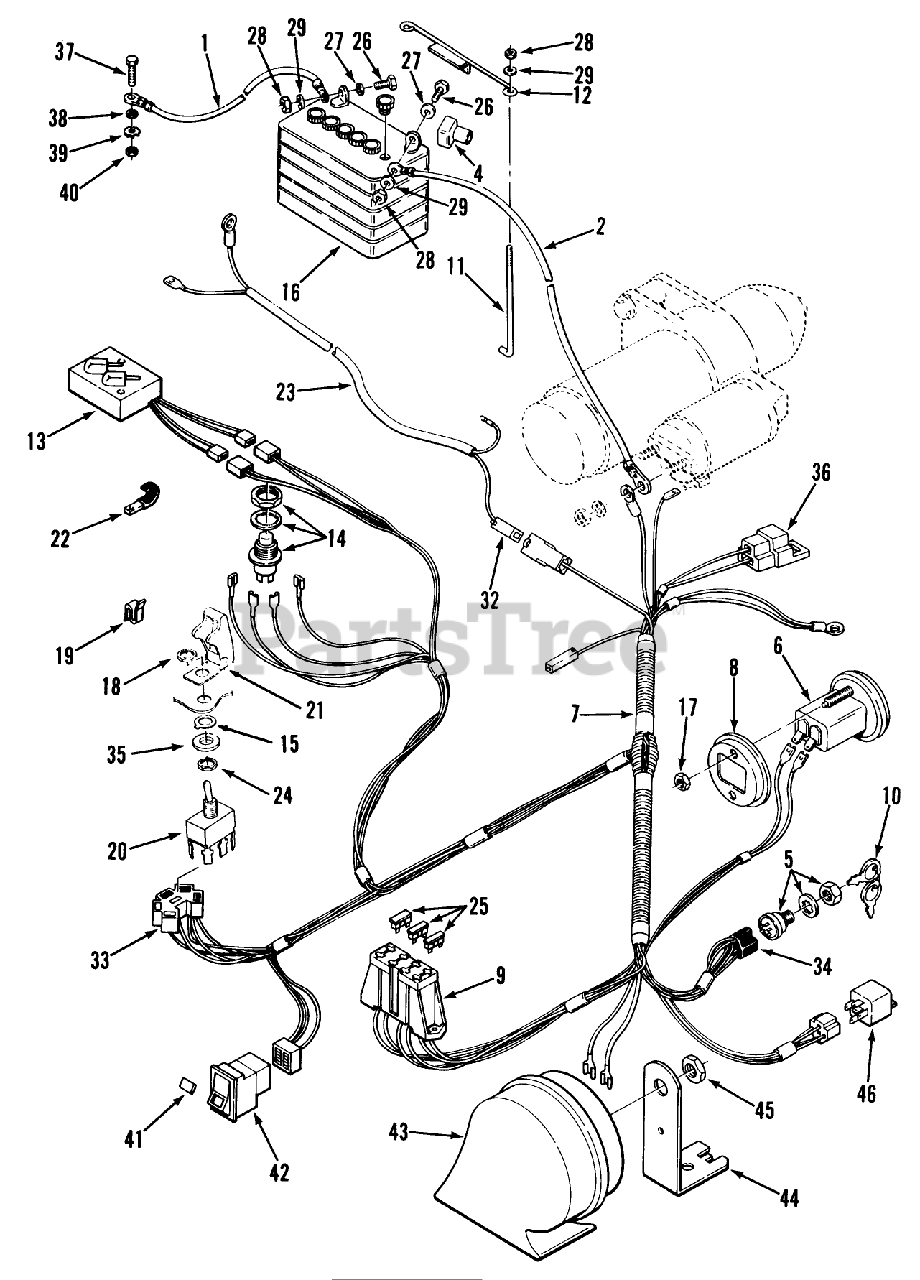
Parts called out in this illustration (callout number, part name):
1	WIRE -BLACK
6	GAUGE-HOURMETER
8	BRKT-GAUGE MOUNTING
11	HOOK-BATTERY RETAIN
12	HOLDDOWN-BATTERY
15	TAB-WASHER
18	*DISC**
19	CLIP-CABLE
20	SWITCH-TOGGLE DPDT
21	COVER-PTO SWITCH
22	CLIP
25	FUSE-BLADE, 15 AMP
33	CONNECTOR 5 WAY
35	WASHER-FLAT
36	CONNECTOR BODY
46	RELAY
